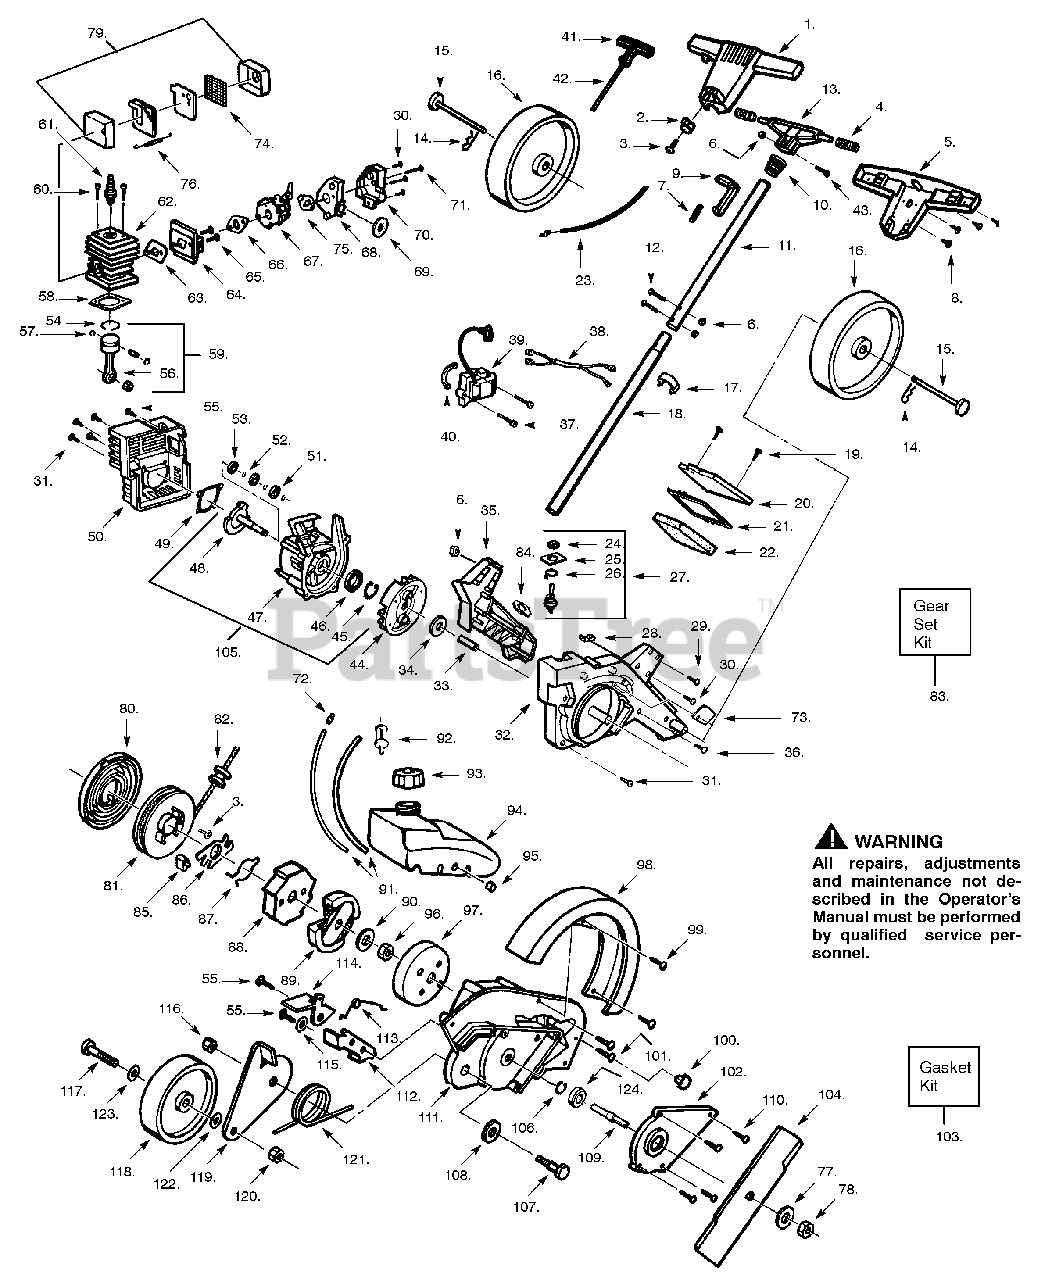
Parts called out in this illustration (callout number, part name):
1	Upper Handle
2	Handle Eyelet
4	Spring Isolator
5	Lower Handle
6	Locknut-Coupling/Shaft
7	Throttle Spring
8	Screw-Handle
9	Throttle Trigger
10	Handle Spring
11	Upper Handle Tube
12	Screw-Shaft
13	Coupling-Handle
14	Bridgepin
15	Axle Pin
16	Rear Wheel
17	Tube Clamp
18	Lower Handle Tube
19	Screw-Filter Cover
20	Air Filter Cover Type 1 & 2
20	Air Filter Cover Type 3
22	Air Filter Foam
23	Throttle Cable
24	Boot w/Nut
25	Switch Indicating Plate
26	Grounding Terminal
27	Switch Grounding Assy
28	Speed Nut
29	Screw-Fan Housing
30	Screw-Fan Housing
31	Screw-Fan Housing/Shroud
32	Fan Housing Kit
33	Flywheel Spacer
35	Axle Cover
36	Screw-Fan Housing
37	Screw-Ignition Module
38	Switch Wire Ass'y.
39	Ignition Module
40	Spacer-Ignition Module
41	Starter Handle
42	Rope Kit
43	Screw-Coupling
44	Flywheel Ass'y.
45	Retaining Ring-C'case
46	C'case Seal
47	Crankcase Ass'y.
48	Crankshaft Ass'y.
49	Gasket-Crankcase
51	Outer Bearing
52	Retaining Ring-C'shaft
53	Inner Bearing
54	Piston Ring
55	Screw-Shroud
56	Connecting Rod Ass'y.
57	Piston Pin Retainer
58	Gasket-Cylinder
59	Piston Kit
60	Screw-Cylinder
61	Spark Plug (RCJ-8Y)
62	Cylinder Kit
63	Gasket-Cylinder/Carb Adaptor
64	Carb. Adaptor
65	Screw-Carb Adaptor
66	Carb. Gasket
67	Carburetor w/Choke Type 1 & 2 (WT-242)
67	Carburetor w/Choke Type 3 (WT-308)
67	Carburetor w/Choke Type 3 (WT-630)
68	Air Box Base
69	Foam Seal
70	Airbox Cover
71	Screw-Airbox Cover
72	Fuel Line Fitting
73	Fuel Line Retainer
74	Muffler Screen
75	Gasket-Carb.
76	Muffler Spring
77	Washer-Blade
78	Nut-Blade
79	Muffler Kit
80	Starter Spring
81	Starter Pulley Kit
83	Gear Set Kit
84	Gasket-Tube
85	Starter Dog
86	Starter Cam
87	Starter Dog Wire
88	Starter Cup
89	Clutch Ass'y.
90	Washer-Belleville
91	Fuel Line Kit
92	Fuel Pick-up Ass'y.
93	Fuel Cap Ass'y.
94	Fuel Tank Ass'y.
95	Fuel Tank Isolator
97	Drum Clutch
98	Front Shield
100	Dustplug
101	Screw-Bearing Holder
102	Bearing Holder Ass'y. Type 1
102	Bearing Holder Ass'y. Type 2 & 3
103	Gasket Kit
105	C'case & C'shaft Ass'y.
106	Retainer Ring
107	Shoulder Bolt
109	Drive Shaft
111	Gear Box Ass'y.
112	Back Plate
114	Height Lever
115	Retainer-Starter Pulley
116	Nut-Swing Arm
117	Bolt-Front Wheel
118	Front Wheel
119	Swing Arm
120	Locknut-Swing Arm
121	Front Axle Spring
122	Washer-Thrust
123	Washer-Flat
124	Washer-Thrust
